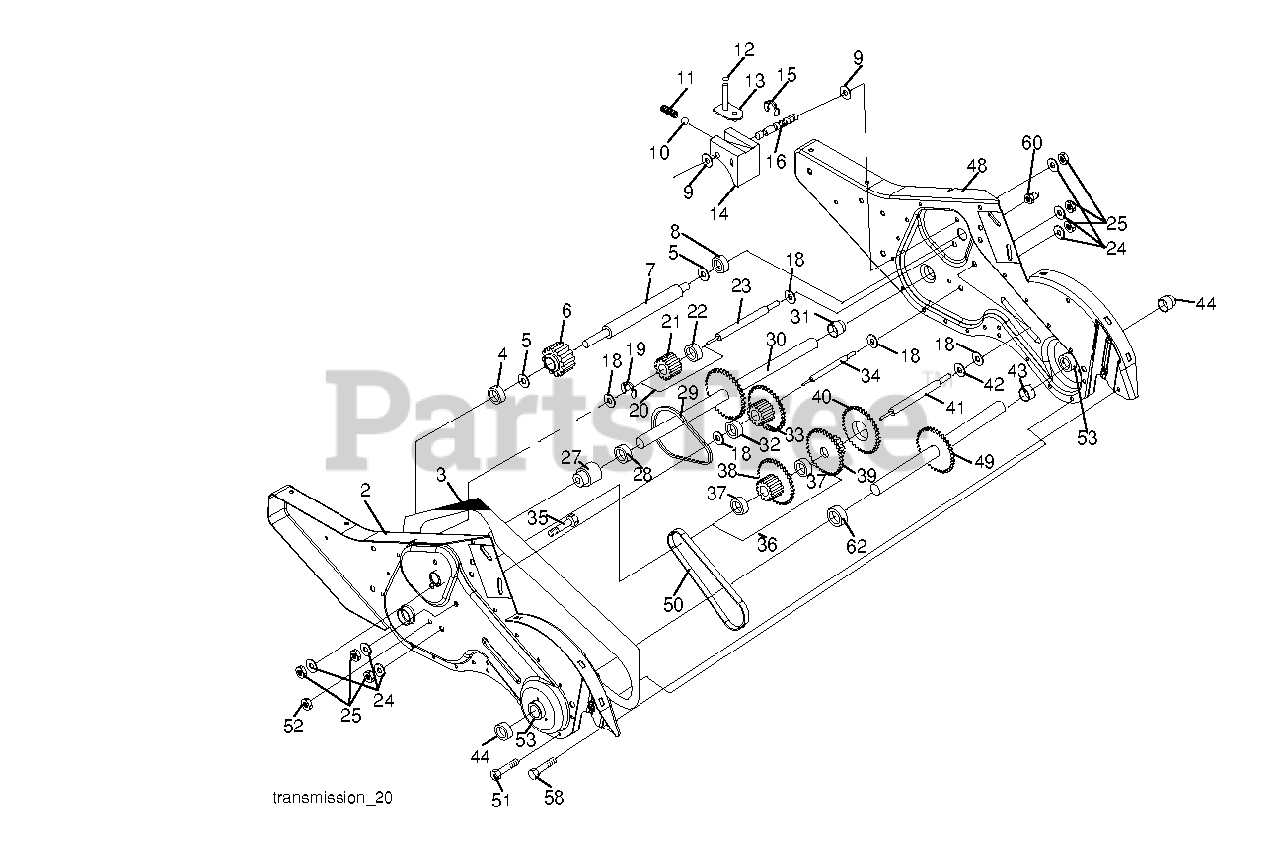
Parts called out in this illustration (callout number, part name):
1	TRANSMISSION ASM.
2	GEARCASE.ASM.CRT.LH.W/BEARING
3	GASKET, GEARCASE
4	NEEDLE BRNG LT
5	THRUST WASHER
6	GEAR.PINION.INPUT
7	SHAFT.INPUT."D".TILLER
8	BEARING TI
9	WASHER, SEAL
10	STEEL BALL KIT
11	SPRING-SHIFT CRT
12	O-RING TI
13	SHIFTING ARM
14	SHIFT FORK TI
15	KLIP RING
16	SHAFT.SHIFTER.TILLER
19	KLIP RING
20	GEAR ASSY CRT
21	GEAR-REV IDLR CRT
22	NEEDLE BEARING TI
23	SHAFT CRT
24	LOCKWASHER
27	BEARING, SHAFT LH CRT
29	CHAIN CRT
30	GROUND SHAFT ASS'Y
31	BEARING, SHAFT RH CRT
32	SPACER TI
33	SPRCKT 8 GEAR CRT
34	SHAFT.SECONDARY.REDUCTION.CRT
35	SCRW WHIZ LOK CRT
36	SPROCKET ASS'Y W/BRG
37	BEARING
38	SPROCKET, TINE
39	GEAR TI
41	SHAFT.REDUCTION.TILLER
42	BRNG RACE T
43	SPACER TI
44	SEAL ASM, OIL
48	GEARCASE.ASM.CRT.RH.W/BEARING
49	SHAFT.ASM.TINE
50	CHAIN.TILLER
51	SCREW
53	BEARING KIT
58	BOLT SHOULDER 1/4-20 UNC X.875
60	FITTING.GREASE.TAPERED
